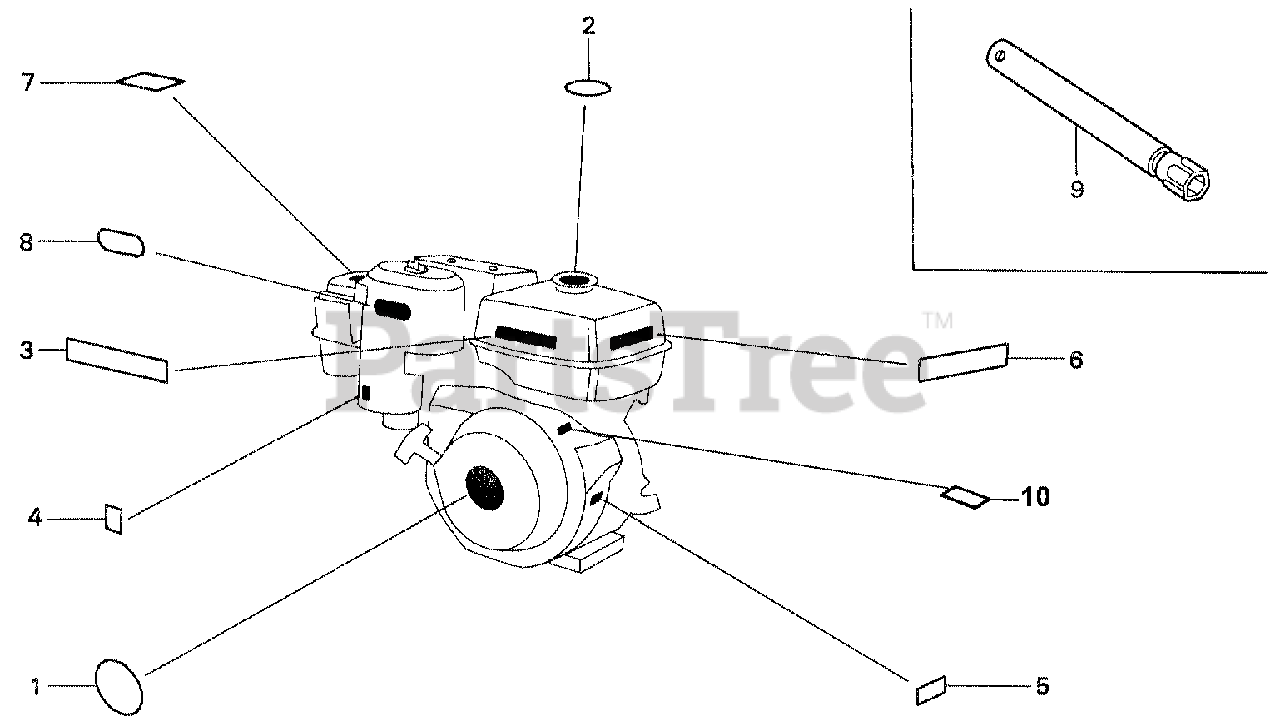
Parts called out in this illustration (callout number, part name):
1	EMBLEM
3	LABEL, CAUTION
4	MARK, CHOKE (EXTERNAL)
6	MARK, OIL ALERT (E)
9	WRENCH, SPARK PLUG
